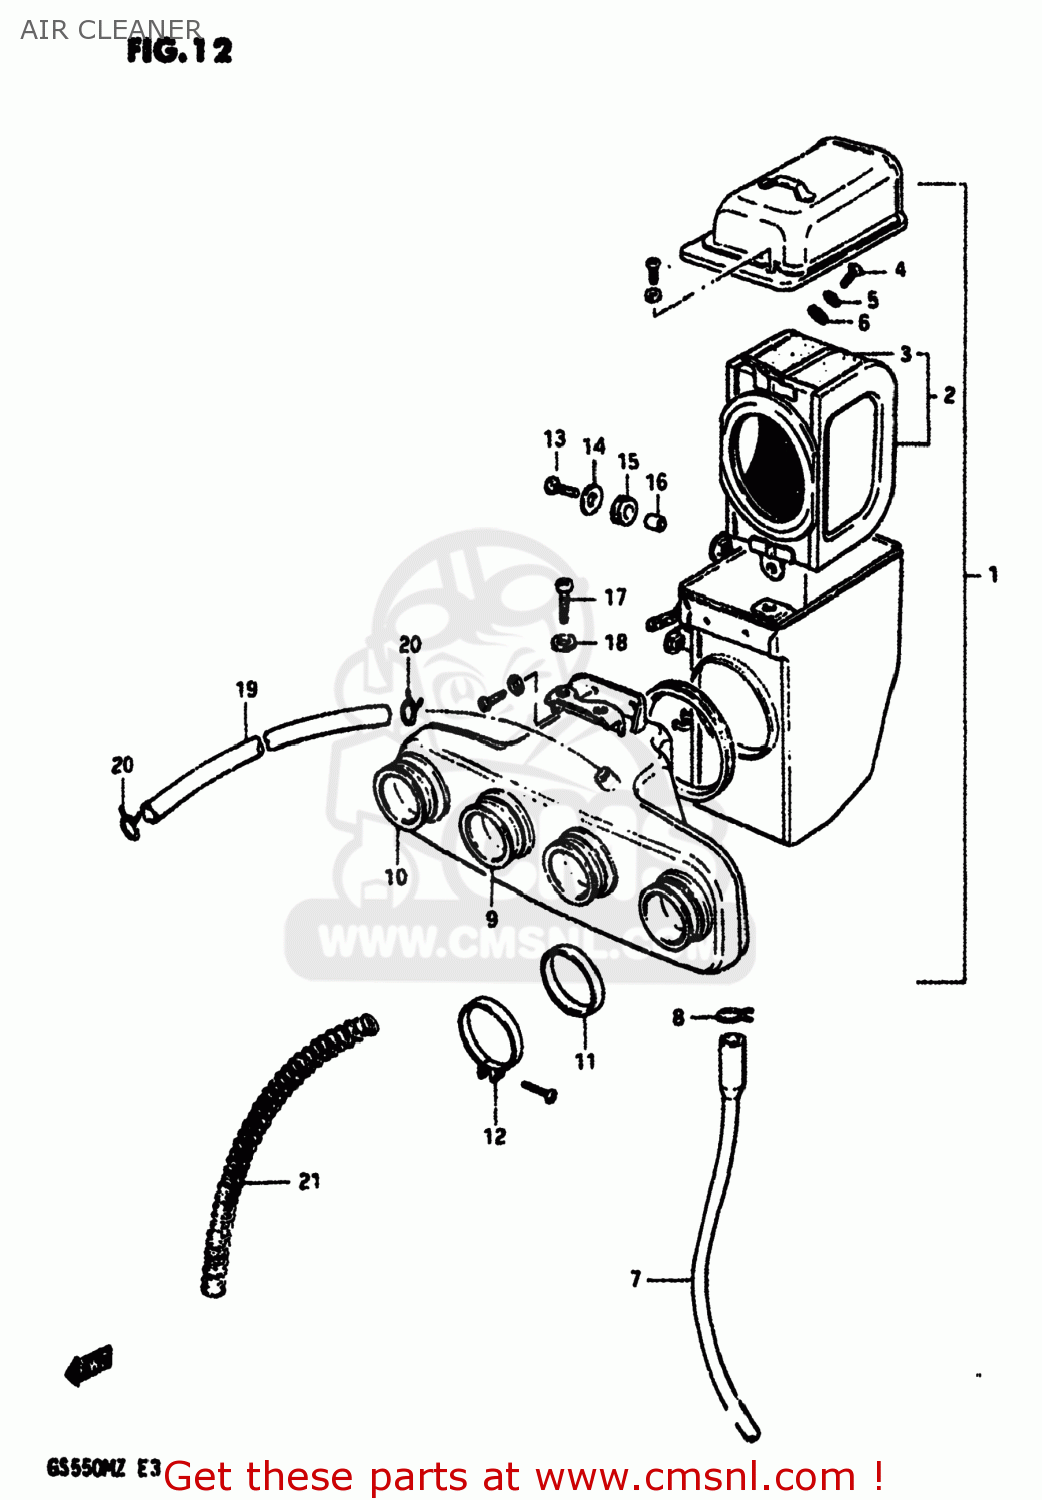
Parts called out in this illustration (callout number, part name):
1	CLEANER ASSEMBLY,AIR
2	FILTER ASSY
3	FILTER
4	SCREW
5	LOCK WASHER
6	WASHER
7	DRAIN TUBE
8	CLIP
9	TUBE,AIR CLEANER OUTLET A
10	TUBE,AIR CLEANER OUTLET B
11	RING,CARBURETOR AIR INLET HOSE
12	CLAMP
13	BOLT
14	WASHER
15	CUSHION
16	SPACER (6.1X9X9)
17	SCREW 6X12
18	WASHER
19	HOSE
20	CLIP
21	SPRING
